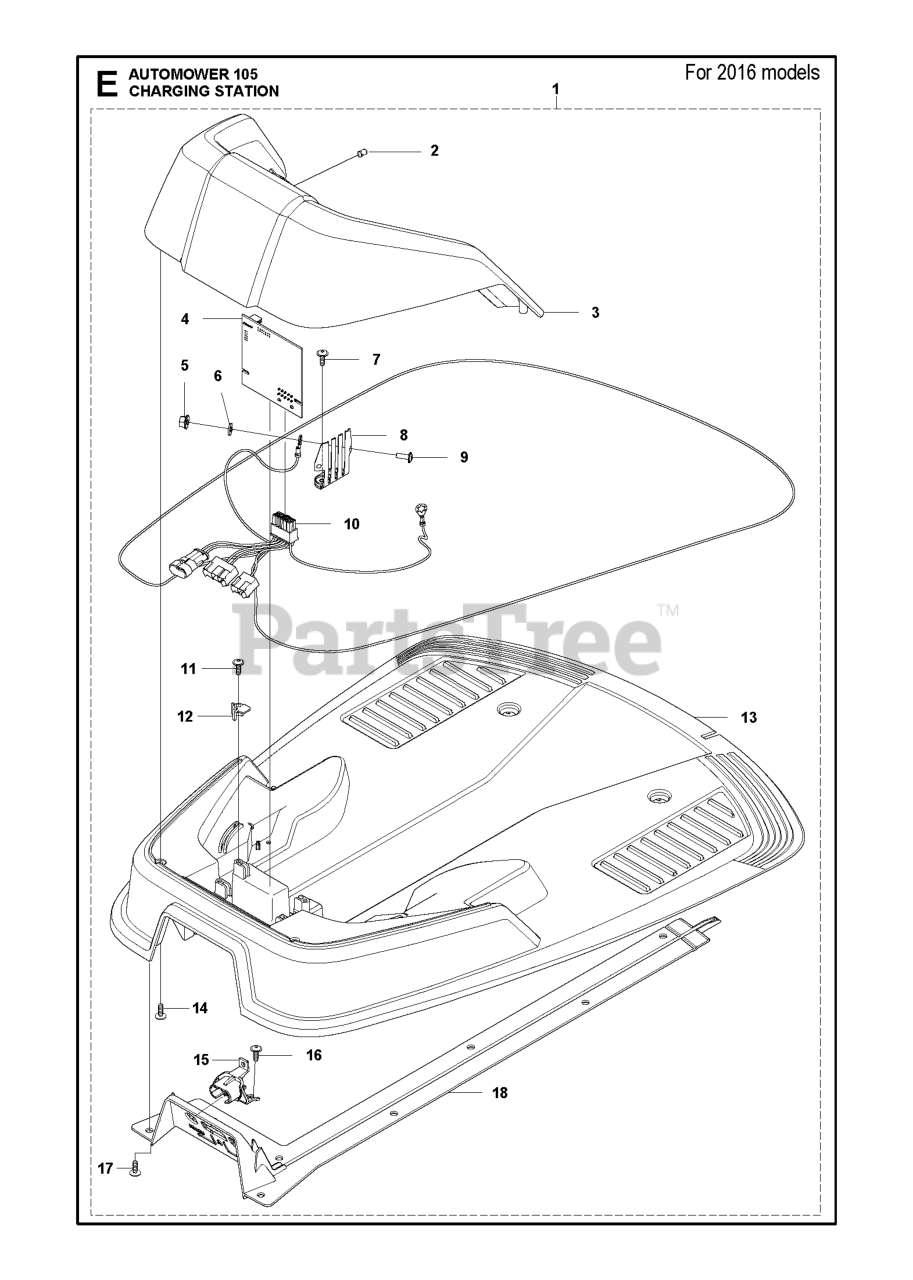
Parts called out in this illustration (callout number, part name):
2	LENS
5	HEXAGON NUT FLANGE M4 A2-70
6	FIBER WASHER
7	SCREW 14MM
8	CONTACT CHARGER STATION CONTAC
9	SCREW ITXPANM M4X12 A2-70 PAT
11	SCREW 14MM
14	SCREW 14MM
16	SCREW 14MM
17	SCREW 14MM
